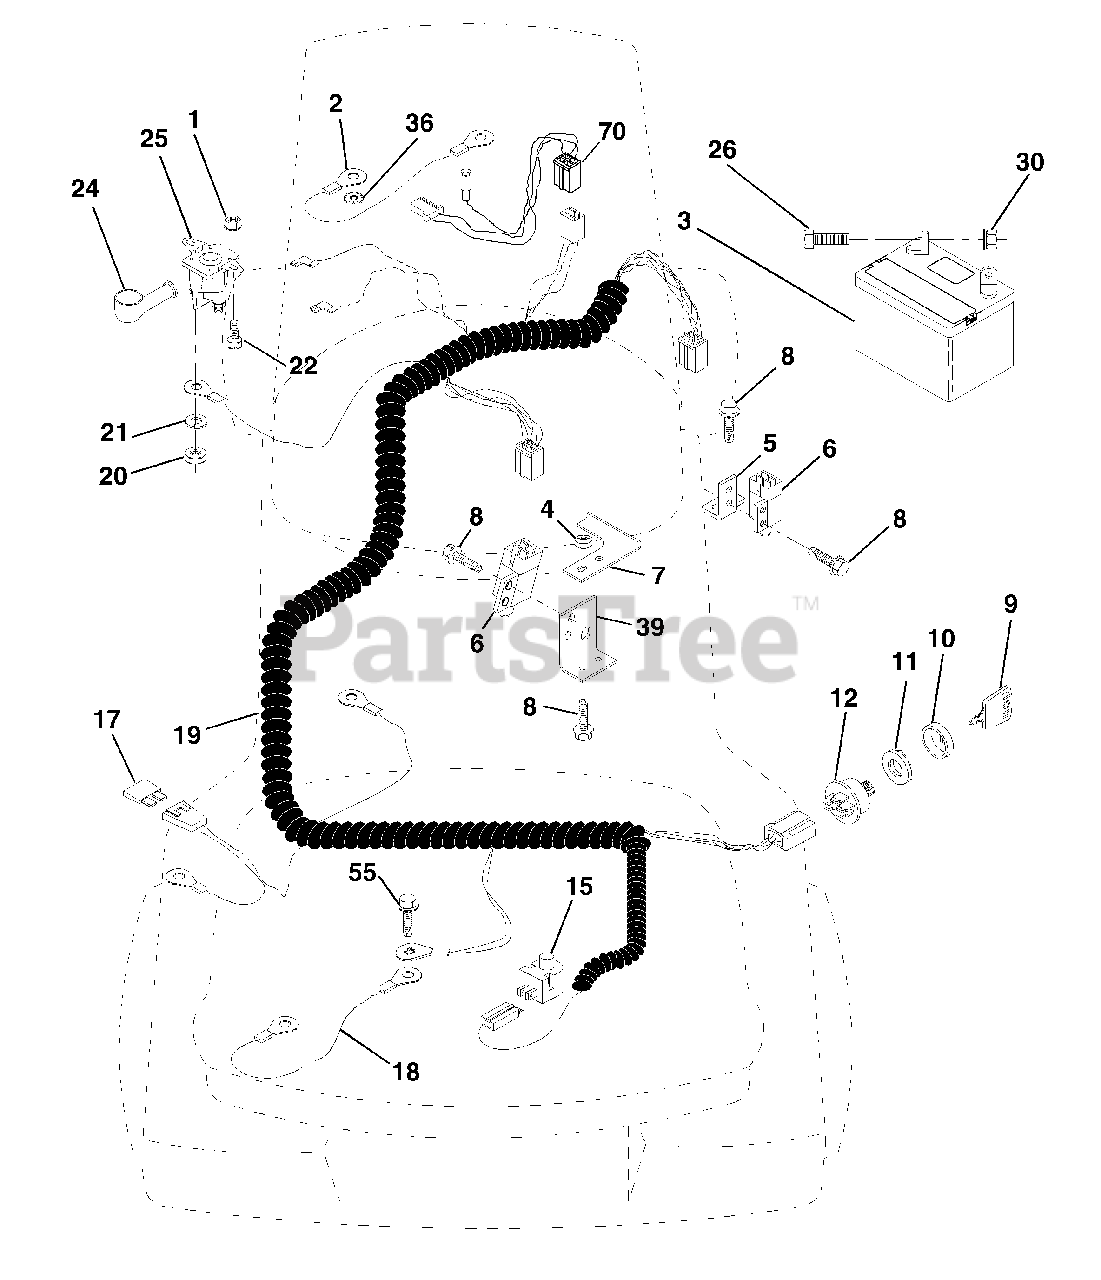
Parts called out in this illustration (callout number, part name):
1	Nut, Hex Keps 1/4-20
2	Assembly, Cable
3	Battery
4	Nut, Lock #10-24 Unc
5	Bracket, Switch
6	Switch, Interlock (4-terminal)
7	Keeper, Actuator
8	Screw, Hex Hd. Tap #10-24 x 1/2
9	Key, Mplded
10	Cover, Key Ignition
11	Nut, Ignition
12	Switch, Ignition
15	Switch, Plunger
18	Assembly, Cable
19	Harness, Ignition
20	Nut, Hex Jam 1/4-20
21	Washer, Lock 1/4
22	Bolt, Fin. Hex 1/4-20 UNC x 1/2
24	Cover, Terminal
25	Solenoid
26	Bolt, Hex Hd. 1/4-20 UNC x 3/4
30	Nut, Keps Hex 1/4-20 UNC
36	Washer Lock Inter. Tooth 1/4
39	Bracket Switch Clutch
55	Screw Thdrol 5/16 - 18 x 1/2
70	Harness Engine
